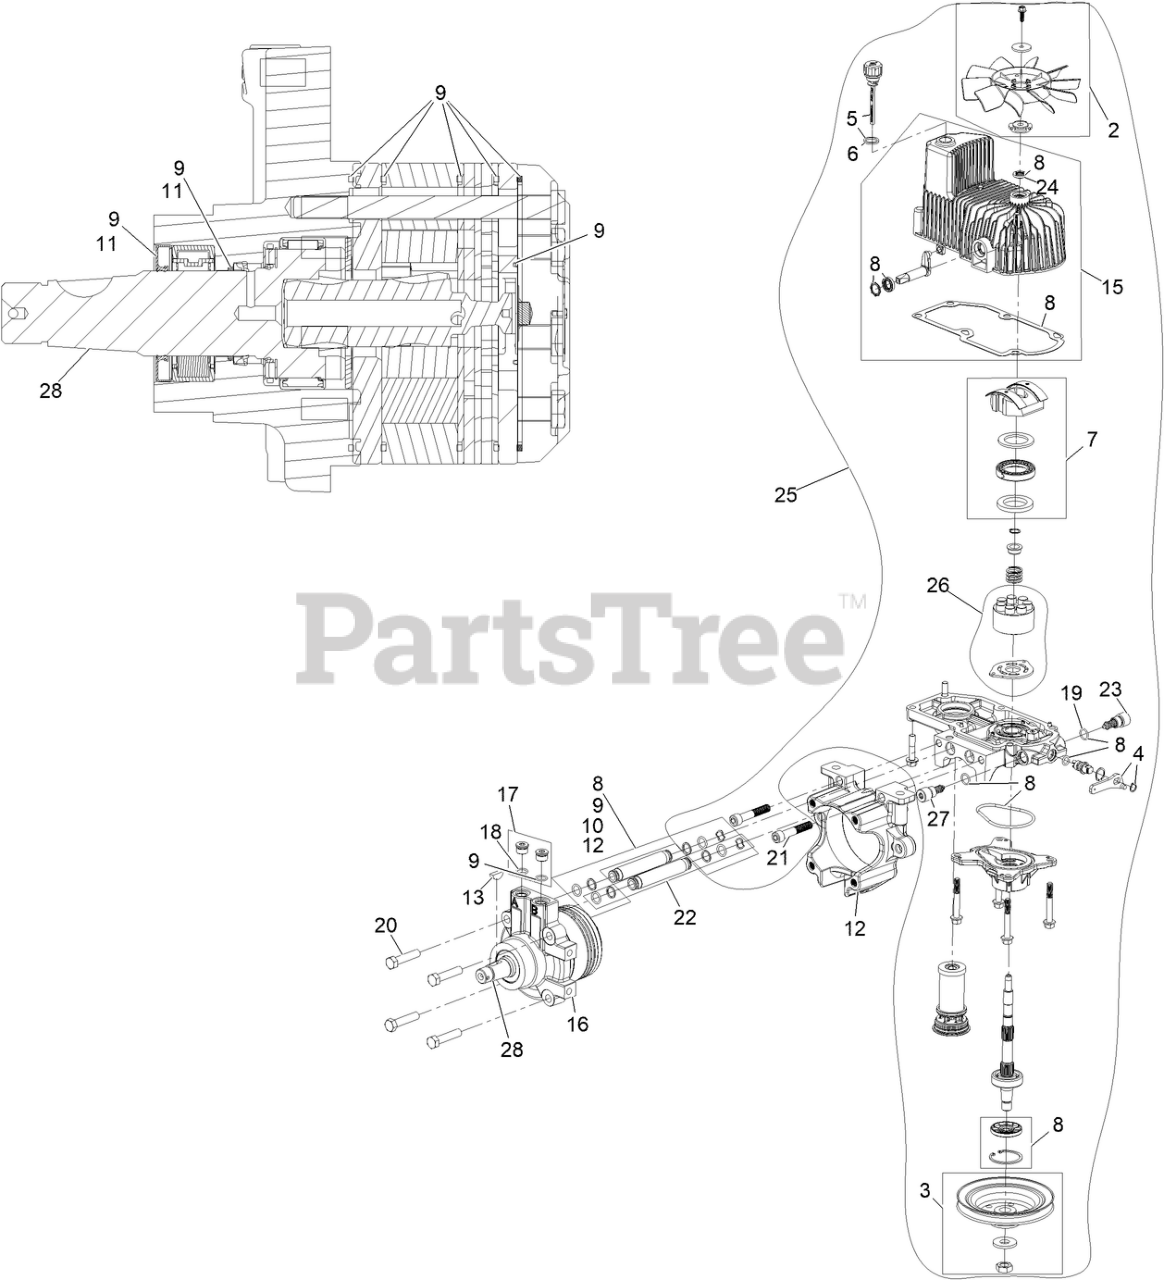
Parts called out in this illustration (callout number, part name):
2	Kit, 7.8 In Fan
3	PULLEY KIT
4	HANDLE-BYPASS VALVE, HYDRO
5	DIPSTICK-HYDRO W/GASKET
6	GASKET-DIPSTICK, HYDRO
7	SWASH BLOCK KIT
8	Kit, Pump Seal
9	MOTOR SEAL KIT
10	TUBE SEAL KIT
11	OUTPUT SHAFT SEAL KIT
12	NOSE CUP-UHT
13	KEY-WOODRUFF
15	Kit, Housing-Hydro LH
16	HYD MOTOR,280CC LH SEALED
17	MAGNETIC PLUGS SERVICE KIT
19	O-RING-CHECK VALVE
20	SCREW HH
21	SCREW-HSH
22	HYDRAULIC TUBE KIT
23	SHOCK VALVE, 16CC HYDRO
24	SEAL-FAN DRIVE
25	Kit, Pump Section 16Cc LH
26	Kit - 16Cc Port Plate,Rotate Grp
27	Shock Valve Orificed 3300
28	OUTPUT SHAFT- TL UHT MOTOR
99	PULLER-PULLEY
